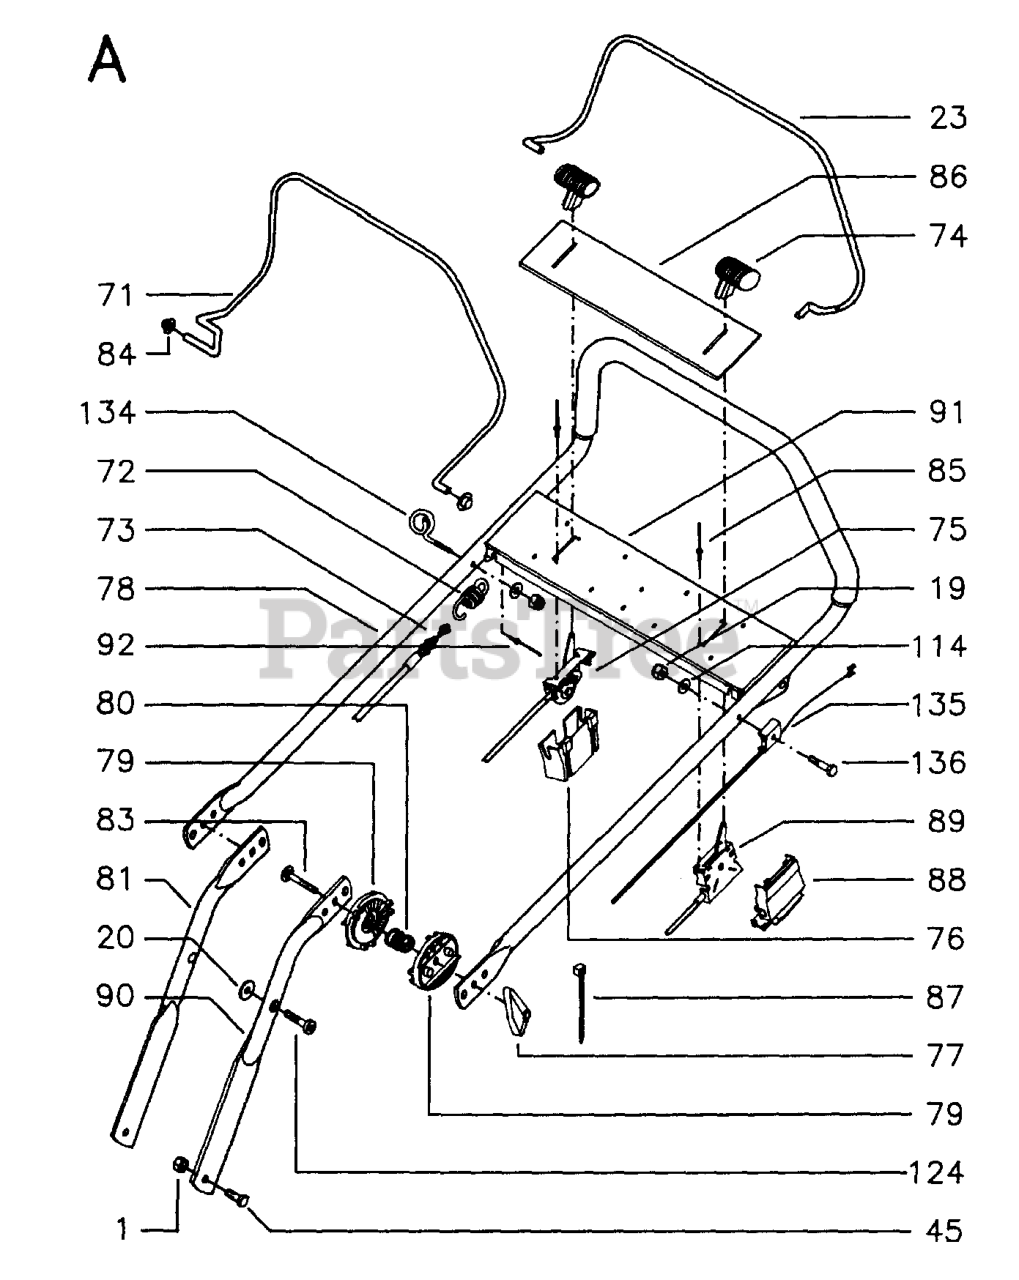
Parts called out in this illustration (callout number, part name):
1	LOCKNUT M8
19	LOCKNUT M6
45	SCREW M6S 8X25
75	CONTROL WIRE
77	WINGNUT
89	CONTROL
90	HANDLE
92	RIVET
134	CABLE GUIDE
136	BOLT FLANGE
